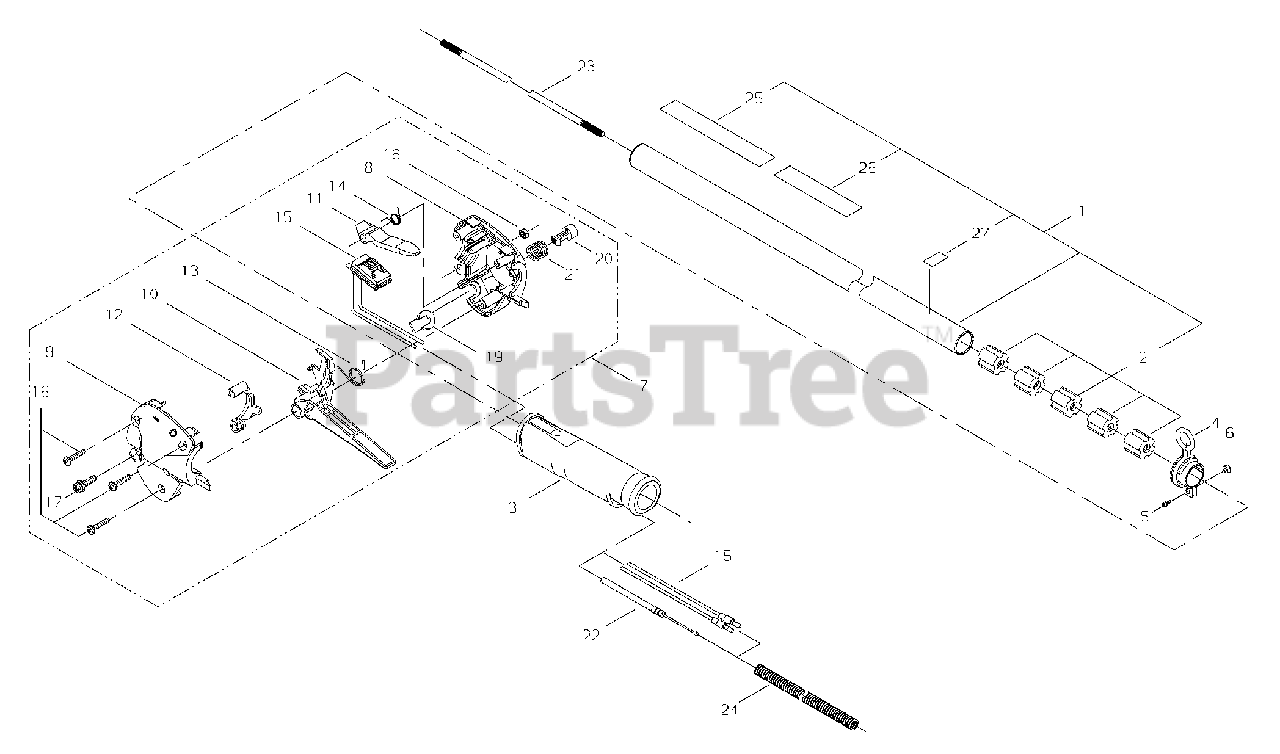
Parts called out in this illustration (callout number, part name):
1	MAIN PIPE ASSY
2	BUSHING
3	GRIP, THROTTLE CONTROL
4	HANGER
5	SCREW - 5X12
7	CONTROL HANDLE ASSY
8	HANDLE, CONTROL - RIGHT
9	HANDLE, CONTROL - LEFT
10	TRIGGER, THROTTLE
11	LEVER, TRIGGER LOCKOUT
12	LOCKOUT, THROTTLE
13	SPRING
14	SPRING
15	SWITCH, IGNITION
16	SCREW - 4X20 -- TAPPING
17	SCREW - 5X20
18	NUT - 5
19	PLUG
20	BUTTON, THROTTLE LOCK
21	SPRING
22	CABLE, THROTTLE
23	PIPE, MAIN
25	LABEL - TRADE
26	LABEL - CAUTION
27	LABEL - CAUTION
